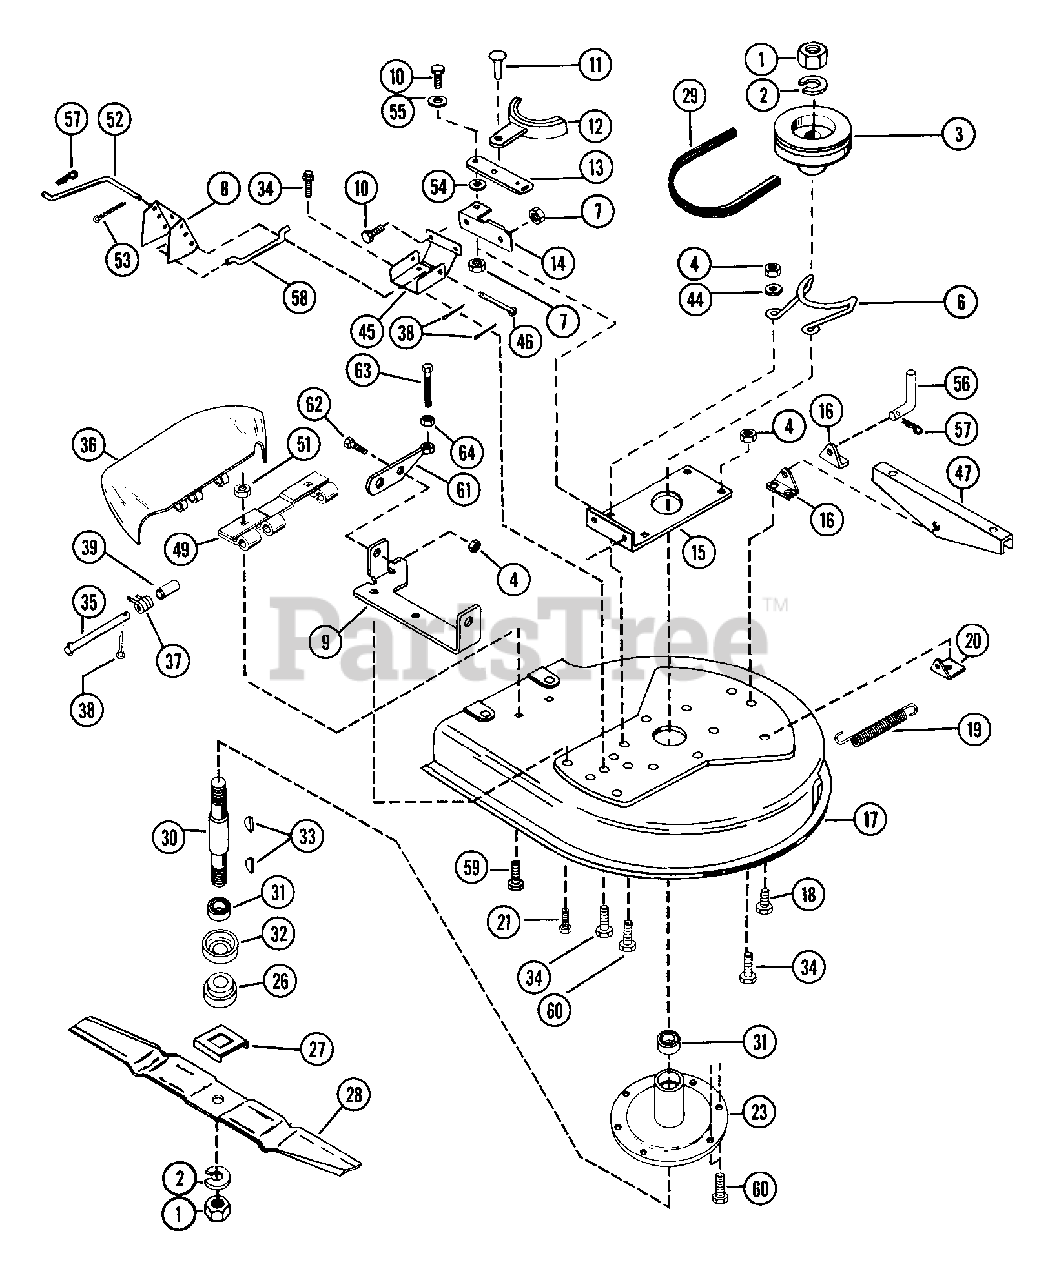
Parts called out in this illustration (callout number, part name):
1	NUT-JAM .75-10 PL
2	WSHR-LK .750X.188 MED PL
3	MOWER SHEAVE
4	NUT-LK-CTR .375-16 GR A PL
6	BELT FINGER
7	NUT-LK .312-18 GR A PL
8	MOWER ENGAGING ARM
9	FRONT BRACKET 26
10	BLT-HEX .31-18X.63 PL GR 2
11	RVT .25X.50 RH ST
12	BLADE BRAKE
13	MOWER BRAKE LEVER
14	BRAKE BRACKET
16	REAR MTG BRACKET
17	26 IN MOWER PAN W/ DECALS
18	BLT-SERHFWH .25-20X.50 PL
19	SG-TENS .072X.51X5.31 WLD 25
20	BRAKE CLIP
21	BLT-SCRHFWH .38-16X.50 PL
23	SPINDLE HOUSING
26	RETAINER HUB
27	BLADE TRAY
28	MOWER BLADE 26
29	V-BELT, 4L-WRAPPED
30	SPINDLE SHAFT
31	BRG-BALL .750X1.781X.61
32	BEARING SLINGER
33	KEY-WDRF .188X.75X.313 SAE 9
34	BLT-SERHFWH .31-18X.50 PL
35	CLEVIS PIN
36	PAN CHUTE EXTENSION
37	SG-TORS .095X.50X 1.0
38	PIN-COTR .09X.75 PL
39	BSHG-SLV .334 X .502 X 1.437
44	WSHR-FL-STL .406X.865X.094 PL
45	PIVOT BRACKET
46	PIN-CLEV .309X3.50 SP
47	SWIVEL BRACKET
49	HINGE PLATE
51	NUT-LK-CTR .250-20 PL
52	MOWER ENGAGEMENT LINK
53	PIN-COTR .12X.75 PL
54	SPACER BUSHING .5 X .32 X .163
55	WSHR-FL-STL .328X1.0X.094
56	CLEVIS PIN
57	PIN-HAIR INT .08X.38X1.42 YWZC
58	MOWER BRAKE LINK
59	BLT-RDHDSQNK .25-20X.50 SHT PL
60	BLT-HEX .38-16X1.00 PL
61	ADJUSTING ARM
62	@BLT-HEX .38-16X.88 PL GR2
63	BLT-HEX .38-16X1.75 PL GR2
64	NUT-JAM .375-16 PL
